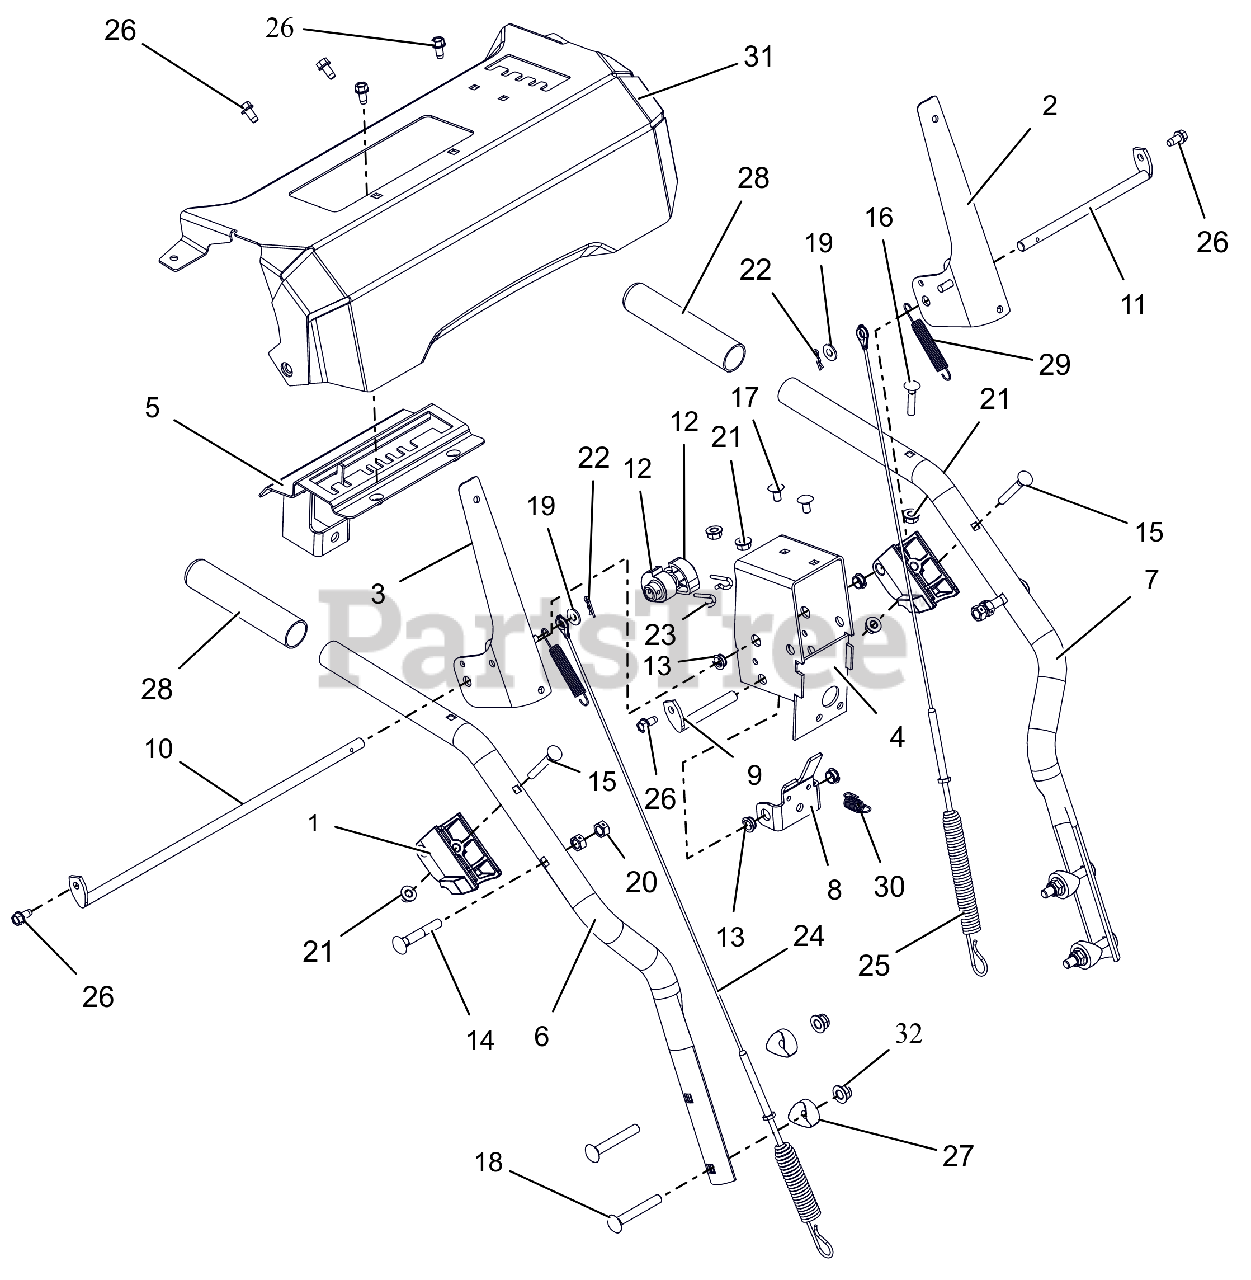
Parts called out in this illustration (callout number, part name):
1	BLOCK, CLUTCH PADDLE
2	LEVER, CLUTCH-LH
3	LEVER, CLUTCH-RH
4	WELDMENT, BRACKET INTERLOCK
5	WELDMENT, DETENT PLATE-COMPACT
6	HANDLEBAR, UPPER - RH
7	HANDLEBAR, UPPER - LH
8	BRACKET, INTERLOCK ARM
9	ROD, PIVOT - INTERLOCK
10	ROD, PADDLE MOUNT - LONG
11	ROD, PADDLE MOUNT - SHORT
12	CAM, INTERLOCK
13	BUSHING, POLYLINER-.38 SNAPIN
14	BLT-RDHDXLSQNK .31-18X2.0 G5YZ
15	BLT-RDHDXLSQNK .25-20X2.0 G5YZ
16	BLT-RDHDXLSQNK.25-20X1.25 G5ZC
17	@BLT-RDHDSQNK .25-20X.50 G5YZ
18	@BLT-RDHDSQNK .31-18X2.25 G5YZ
19	@WSHR-FL-STL.281X.62X.065 YWZC
20	@NUT-LK-CTR .31-18 YWZC
21	@NUT-LK-TOP-FLG .25-20 YWZC
22	PIN-HAIR INT .06X.18X.77
23	PIN, SPRING CLIP
24	CABLE, AUGER (DELUXE & PRO)
25	CABLE, UPPER TRACTION
26	SCR-TAP .25-20X.50 HWH TR YWZ
27	SPACER, HANDLEBAR
28	GRIP,HANDLE-GRAY
29	SPRING, EXTENSION
30	SPRING-EXT .047X.438X1.45
31	CONTROL PANEL W/DECAL, BRUSH
32	@NUT-LK-NYL-FLG .31-18 YWZC
